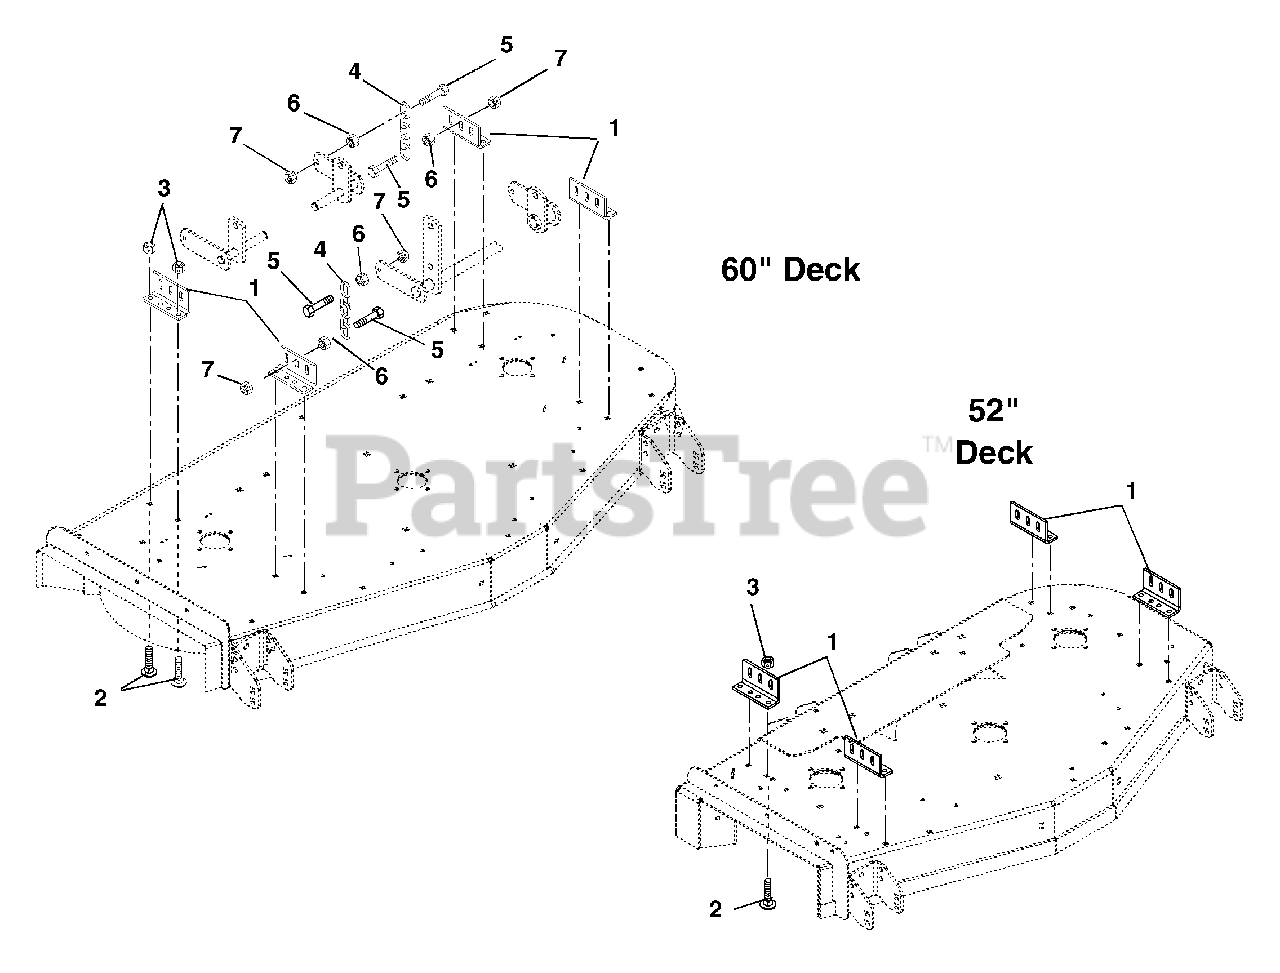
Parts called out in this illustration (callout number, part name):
1	MOWER MTG BRKT - ORANGE
2	@BLT-RDHDSQNK .38-16X1.00 G5YZ
3	@NUT-LK-TOP-FLG .38-16 YWZC
4	CHAIN, LINK
5	@BLT-HEX .50-13X2.00 GR5 YWZC
6	NUT-SPNLK-FLG .50-13 YWZC
7	@NUT-LK-TOP-FLG .50-13 YWZC
